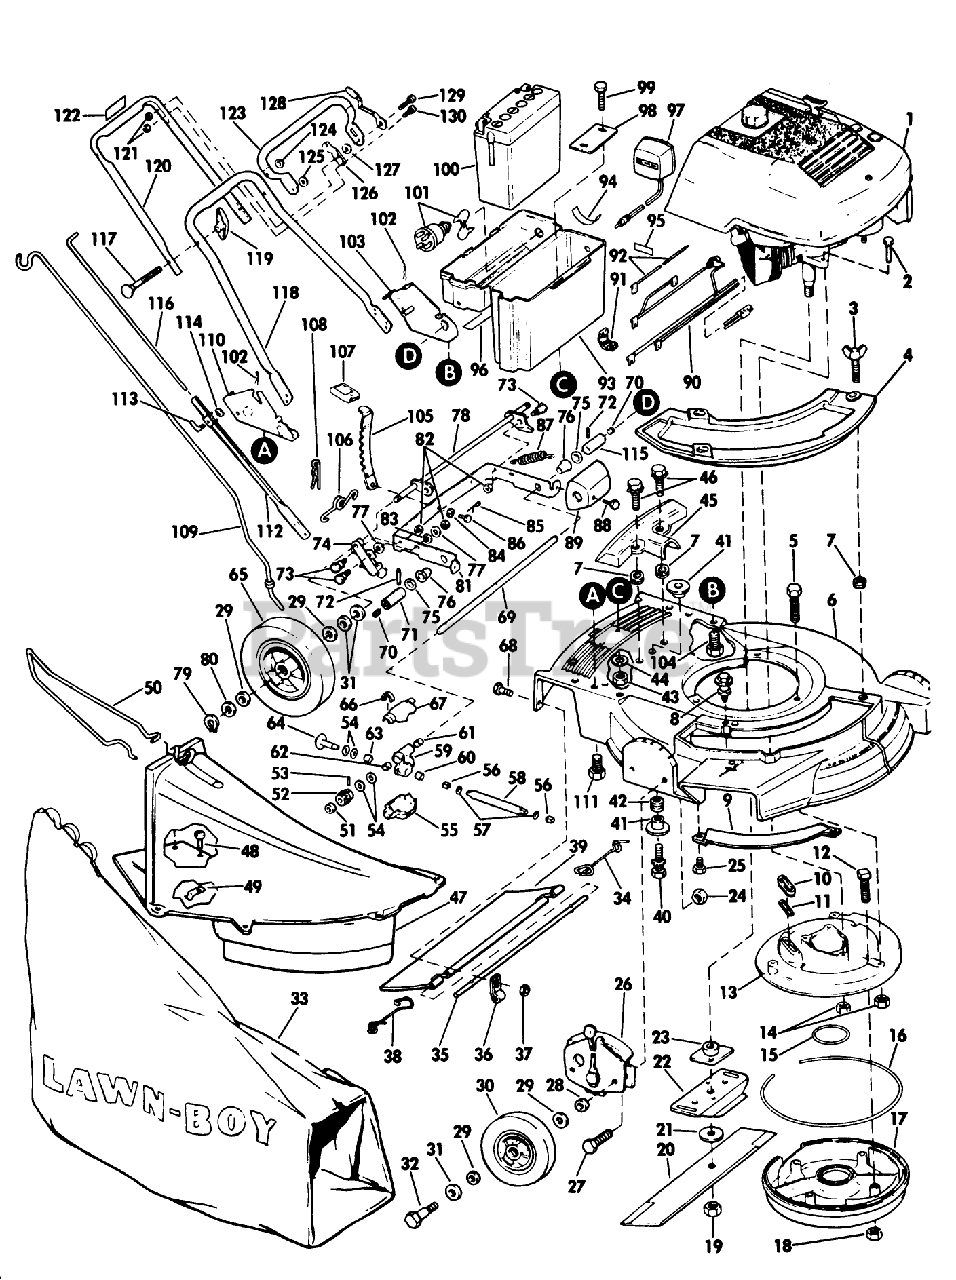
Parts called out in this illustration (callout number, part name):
2	BOLT F
3	WING SCREW LAWRE
5	SCREW V
9	BAR-TOE
10	SLEEVE
11	GASKET S
12	SCREW
14	NUT-LOCK F
16	Gasket Muffler (outside)
18	LOCKNUT E
19	NUT-BLADE
21	WASHER
23	PLATE AND COLLAR ASM
24	NUT
28	WASHER WROUGHT
29	WASHER
31	SPACER
32	BOLT WHEEL
33	ORD LB 89802 WHOLE GOODS
34	SPRIG T/SHLD ASOC
35	ROD 21" ADVANCE
36	CLAMP ROD KMC
38	SPRING;TRAILING SHIELD RH
41	SPACER ECK PRES
42	GROMMET
44	WASHER
45	COVER
46	SCREW SEMS TRM HEX HD
51	WASHER
53	ROLL PIN
54	THRUST WASHER
56	BUSHING
57	O Ring
63	NEEDLE BEARING
67	GEAR COVER UPPER
70	GREASE PLUG
72	PIN
73	BOLT RB&W
77	WASHER S
79	RET RING
80	SPACER
82	STOP NUT
84	WASHER SPRING LAR
86	PIN
87	SPRING
89	GUARD
93	Battery Box Decal Assy.
97	BATTERY CHARGER
102	HAIR PIN
104	SCREW
105	LEVER
106	SPRING N.A.S
107	KNOB
109	ROD GRASSBAG
111	SCREW
116	ROD CONTROL
119	NUT-WING
120	HANDLE
125	WASHER M
128	KNOB & SPRING
129	BOLT RB&W
